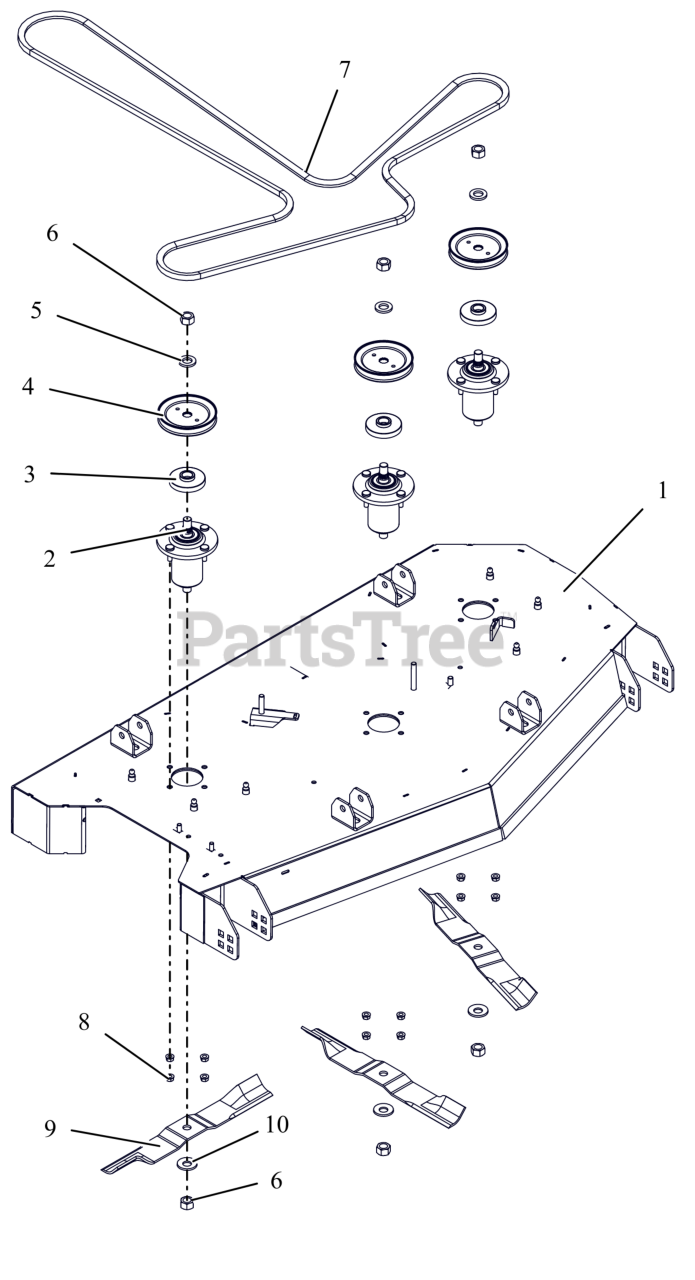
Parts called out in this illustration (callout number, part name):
1	KIT-GRAVELY DECK 48" W/ DECALS
2	ASM, ALUMINUM SPINDLE SUB
3	SHIELD, DUST
4	PULLEY-V-4.50 ODX.625SPLINE ID
5	SPCR- .735 X 1.313 X .165
6	NUT-STD .625-18 ZCC
8	NUT,LK-CTR-FLG .31-18 GF ZCC
9	BLADE- 16.5" MOWER (HI-LIFT)
10	WSHR-BLVL .669X1.535X.138
